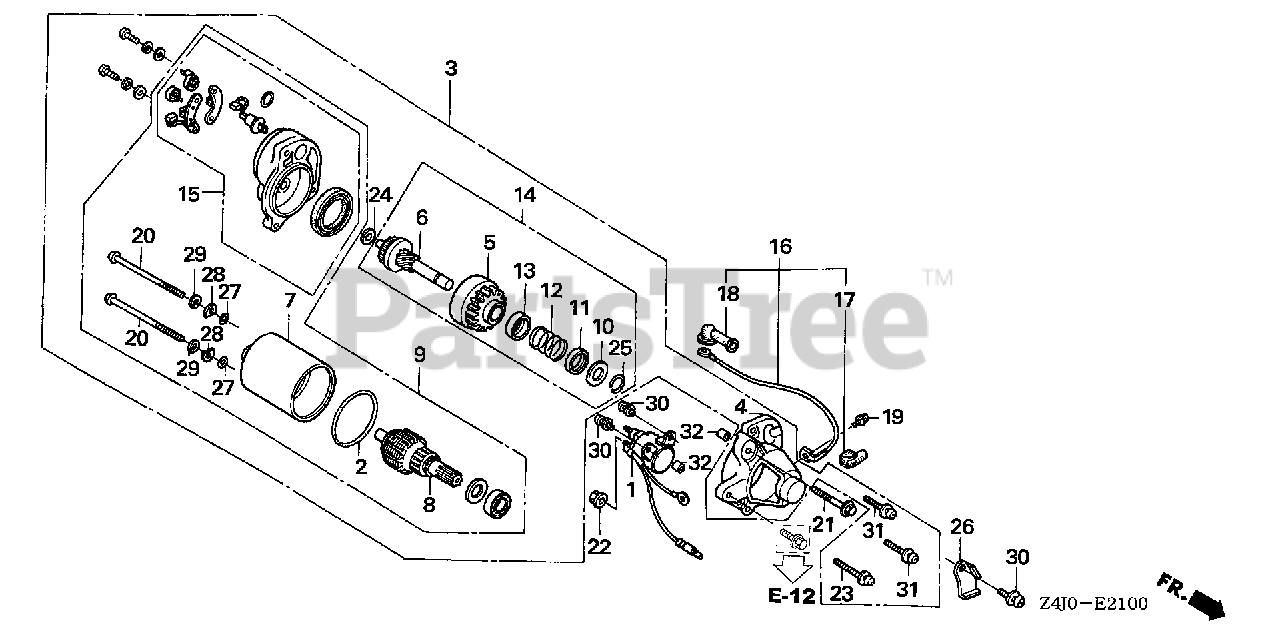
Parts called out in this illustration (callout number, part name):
1	SWITCH, STARTING MAGNET
2	O-RING Use from Engine SN 2664637.
3	MOTOR UNIT, STARTER
4	COVER, GEAR
5	PINION ASSY.
6	SHAFT UNIT, GEAR
7	YOKE ASSY.
8	ROTOR ASSY.
9	MOTOR ONLY
10	PIECE A, STOPPER
11	PIECE B, STOPPER
12	SPRING, RETURN
13	COVER, SPRING
14	GEAR ASSY.
15	BRACKET, FR.
16	WIRE, MAGNETIC SWITCH
17	COVER, MAGNET SWITCH TERMINAL
18	COVER, STARTER MOTOR TERMINAL
19	SCREW-WASHER (5X8)
20	BOLT, SETTING
21	BOLT, FLANGE (6X32)
22	NUT-WASHER (6MM)
23	SCREW-WASHER (5X30)
24	WASHER, PINION
25	CIRCLIP (10.2MM)
26	HOLDER, HARNESS
27	O-RING
28	WASHER, SPECIAL
29	WASHER, SPRING
30	SCREW-WASHER (5X14)
31	SCREW-WASHER (5X20)
32	PIN A, DOWEL (8X10)
